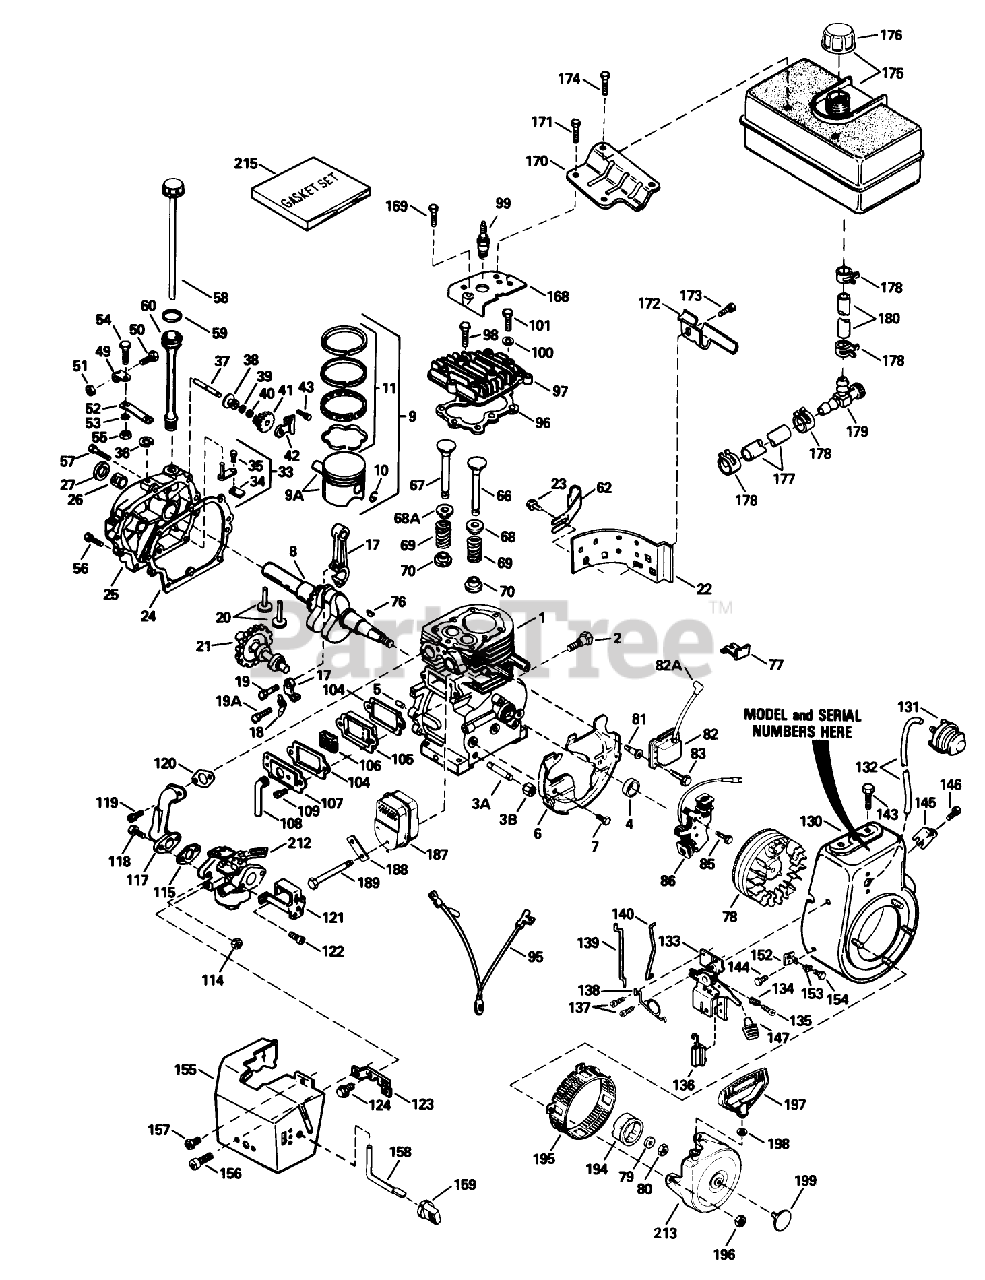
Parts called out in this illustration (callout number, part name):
1	Cylinder Asm (Includes 2, 20, 72)
2	Screw (1/4-20x1/2)
3A	Nipple-Pipe
3B	Cap-Pipe
4	Seal-Oil
5	Pin-Dowel
6	Baffle-Blower Housing
7	Screw (1/4-20x19/32)
8	Crankshaft
9	Piston, Pin Ring Assy.(Std.) (Incl. Ref. #24A, 25 26)
9A	Piston Pin Assy. (Std.) (Incl. Ref. #26)
11	Ring Set (Std.)
17	Rod Assy., Connecting (Incl. Ref. #28 28A)
18	Dipper-Oil
19	Bolt-Rod
19A	Bolt-Rod
20	Lifter-Valve
21	Camshaft (MCR)
22	Extension-Housing, Blower
23	Screw
24	Cylinder Cover Gasket
25	Cover-Cylinder (Includes 71, 75, 80)
26	2025A77 WIZARD ROTA
27	Seal-Oil
33	Rod, Governor (Incl. Nos.62 63)
34	Yoke-Governor
35	Screw (6-40x5/16)
36	Ring-Retaining
37	Shaft-Governor
38	Spool-Governor
39	Washer
40	Ring-Retaining
41	Gear Assy., Governor (Incl. Ref. #45)
42	Bracket-Gear, Governor
43	Screw (10-24x1/2)
49	Clamp-Lever, Governor
50	Screw
51	Nut-Lock
52	Lever-Governor
53	Washer-Lock
54	Screw
55	Nut-Lock
56	Screw (1/4-20x1-11/16)
57	Screw (1/4-20x1-3/16)
58	Dipstick
59	O-Ring
60	Tube-Fill, Oil
62	Clip-Tube, Fill
66	Valve, Exhaust (Standard)(Incl. No. 9)
67	Valve, Intake (Std.) (Incl. Ref. #58)
68	Cap-Spring, Valve
68A	Seal-Intake Valve
69	Spring-Valve
70	Keeper-Spring, Valve
76	Key-Flywheel
77	Clip-Wire
78	Flywheel ASM
79	Washer-Belleville
80	Nut-Flywheel
82	Solid State ASM
82A	Cover-Spark Plug
83	Screw
85	Screw (1/4-20 x 3/4)
86	Coil-Alternator, 18 Watt (Includes 323)
95	Ground Wire
96	Gasket-Cylinder Head
97	Head Cylinder
98	Screw (5/16-18x1-1/2)
99	Spark Plug-Resistor (R J19 L M)
100	Washer-Flat
101	Screw (5/16-18x1-25/32)
104	Gasket-Cover, Valve
105	Body-Breather
106	Element-Breather
107	Cover-Valve
108	Tube-Breather
109	Screw
114	Nut and Lock Washer (1/4-28)
115	Gasket-Carburetor To Intake Pipe
117	Pipe-Intake
118	Screw (1/4-28x1)
119	Screw (T-30, 5/16-18x1-3/32)
120	Gasket-Pipe, Intake
121	Bracket-Choke
122	Screw (10-32 x 1/2)
123	Bracket-Carburetor
124	Screw (8-32x27/64)
130	Housing-Blower
131	Primer-Asm
132	Line-Primer
133	Bracket-Control (Includes 19, 203, 204, 206)
134	Spring-Compression
135	Screw
136	Terminal
137	Screw (10-32 x 1/2)
138	Spring-Throttle
139	Link-Governor
140	Link-Throttle
143	Screw (5/16-18x3/4)
144	Screw
145	Screw
146	Screw (8-32 x 3/8)
147	Knob-Control
152	Bracket
153	Grommet
154	Screw (8-32 x 3/8)
155	Cover-Carburetor
156	Screw (10-32 x 3/8)
157	Screw (10-32x1/2)
158	Rod-Choke
159	Knob-Control
168	Cover-Cylinder Head
169	Screw (1/2-20x5/8)
170	Bracket-Tank, Fuel (Black)
171	Screw
172	Bracket-Tank, Fuel
173	Screw (1/4-20x19/32)
174	Screw (1/4-15x7/8)
175	Tank-Fuel (Includes 292, 301)
176	Cap-Fuel
177	Line-Fuel
178	Clamp-Line, Fuel
179	Valve-Shut Off
180	Line-Fuel (8.62)
187	Muffler
188	62513 SNWTHWR W/284
189	Screw
194	Cup-Starter
195	Screen-Starter
196	Nut and Lock Washer (1/4-28)
197	Handle-Starter, Mitten Grip
198	Washer
199	Plug Starter
212	Carburetor (Incl. Ref. #184)
213	Starter-Rewind
215	Gasket Set (Incl. items marked *)
